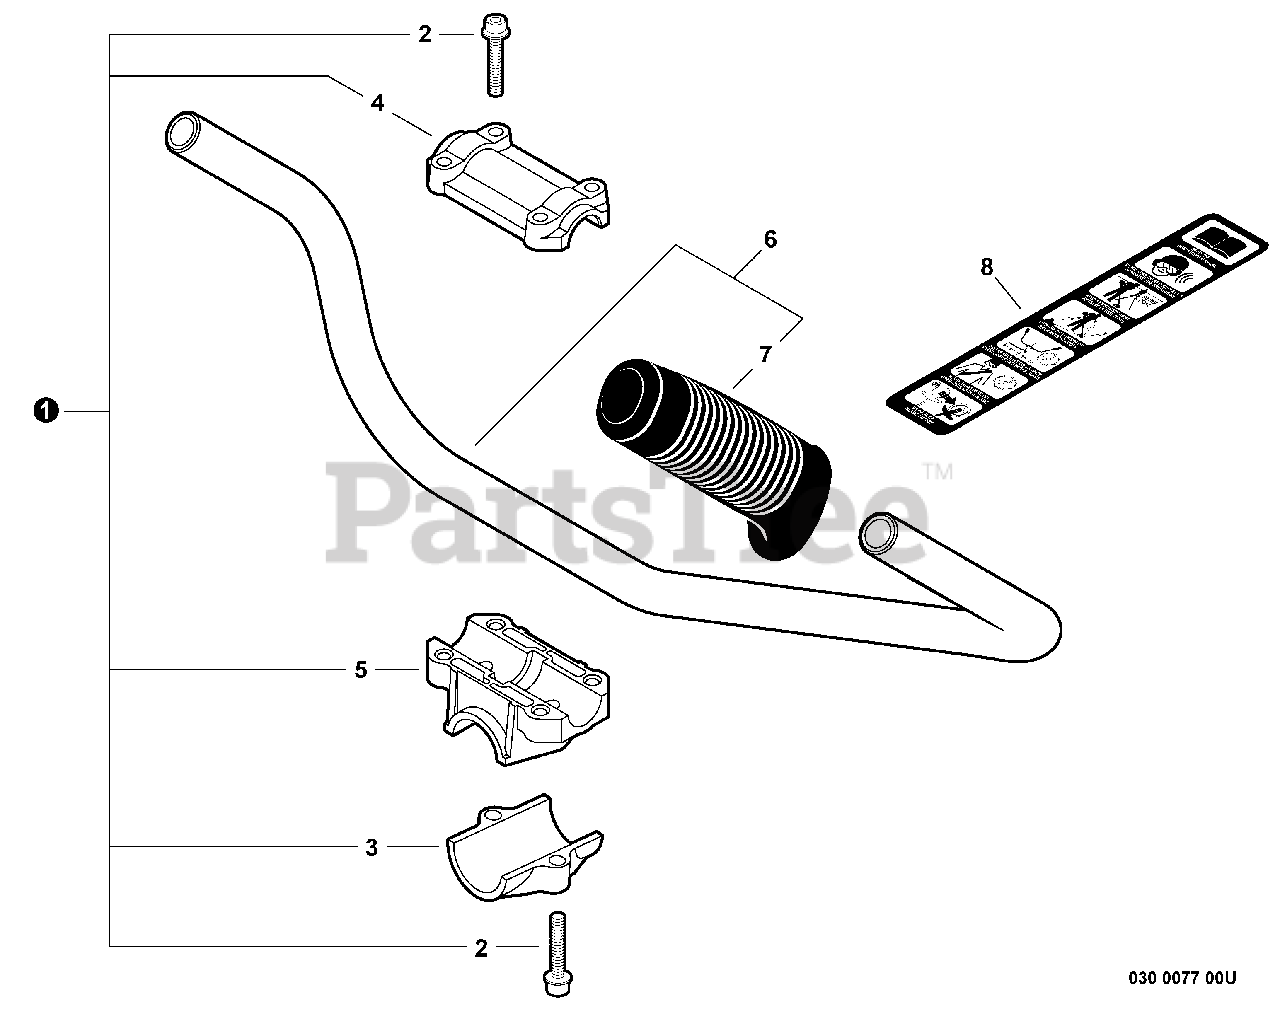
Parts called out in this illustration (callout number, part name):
1	BRACKET KIT, HANDLEBAR
2	BOLT M5×25
3	BRACKET, MOUNTING
4	BRACKET, UPPER
5	BRACKET, LOWER
6	HANDLEBAR ASSY
8	LABEL, CAUTION (BLADE CAPABLE)
